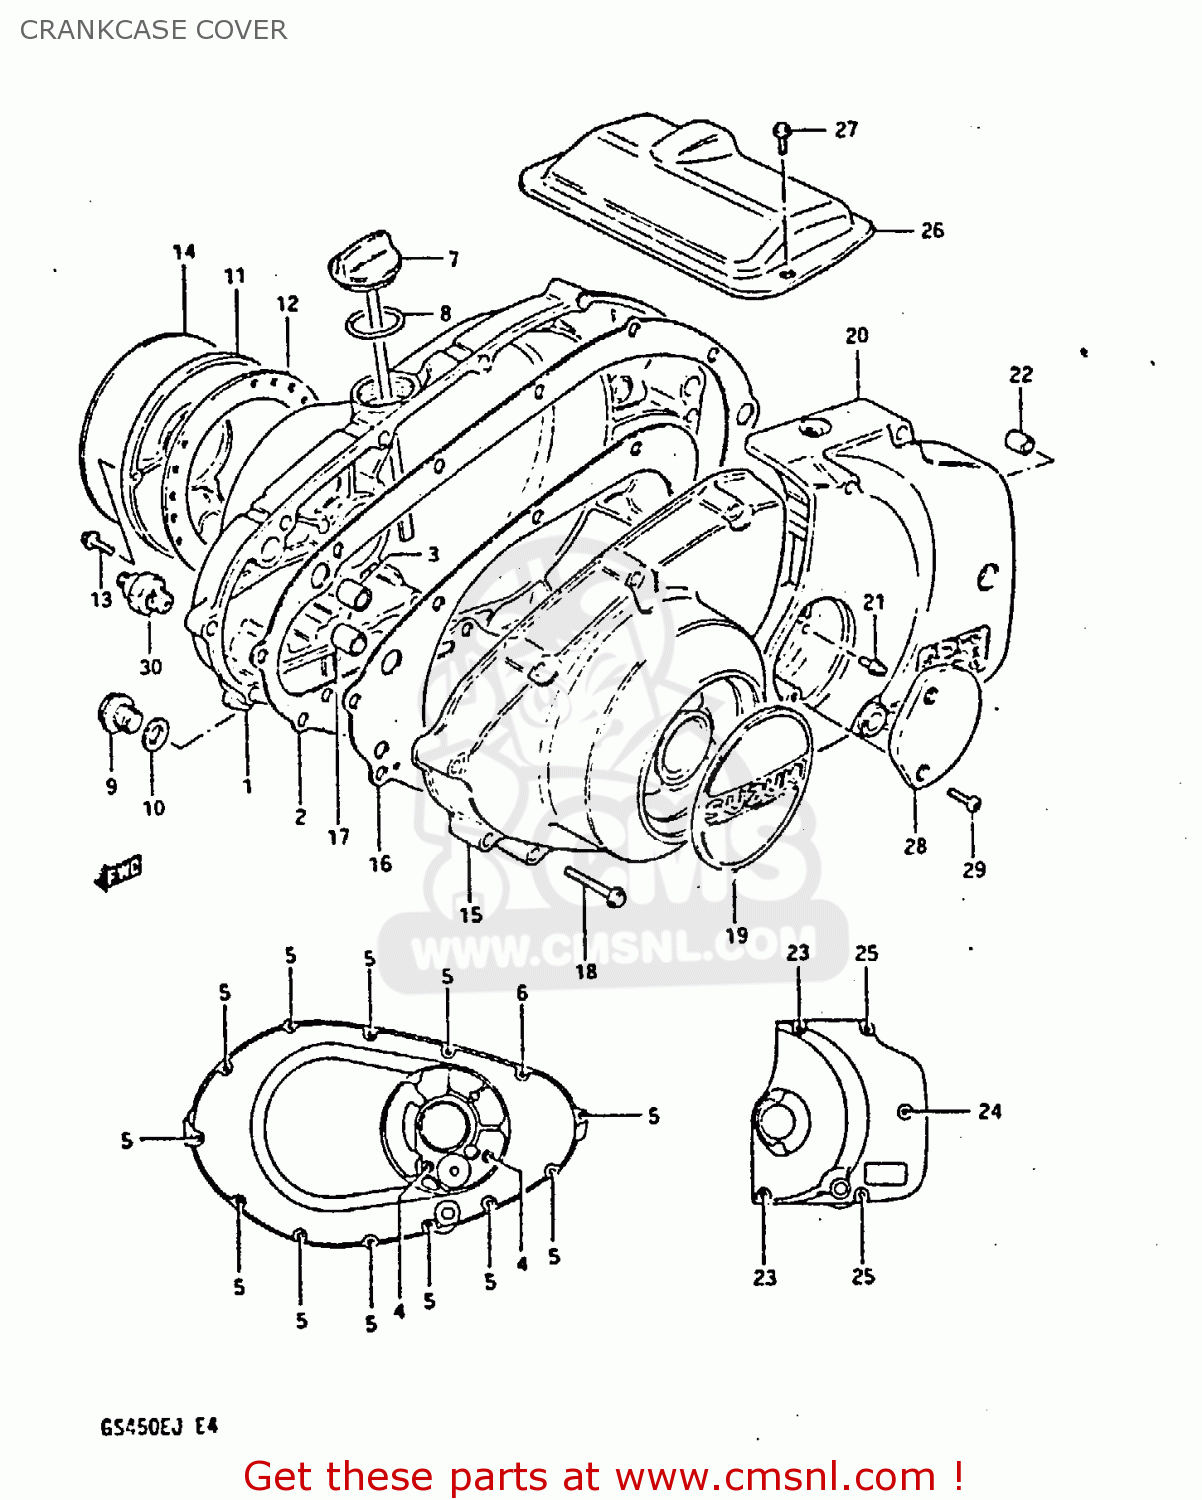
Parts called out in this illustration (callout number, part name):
1	COVER,CLUTCH
2	GASKET,CLUTCH COVER (MCA)
3	PIN
4	BOLT (6X55)
5	BOLT 6X35
6	BOLT 6X25
7	GAUGE,OIL LEVEL
8	O-RING
9	PLUG (14X12)
10	GASKET(14X19.2X2) (NAS)
11	COVER,CONTACT
12	GASKET,CONTACT (MCA)
13	BOLT 5X16
14	EMBLEM,MAGNETO COVER
15	COVER,MAGNETO
16	GASKET,MAGNETO COVER (MCA)
17	PIN
18	BOLT 6X35
19	EMBLEM,MAGNETO COVER
20	COVER, ENGINE SPROCKET
21	NIPPLE
22	PIN
23	BOLT
24	BOLT 6X50
25	BOLT 6X40
26	COVER,STARTER MOTOR
27	BOLT
28	CAP, CLUTCH RELEASE
29	SCREW
30	SWITCH ASSEMBLY
